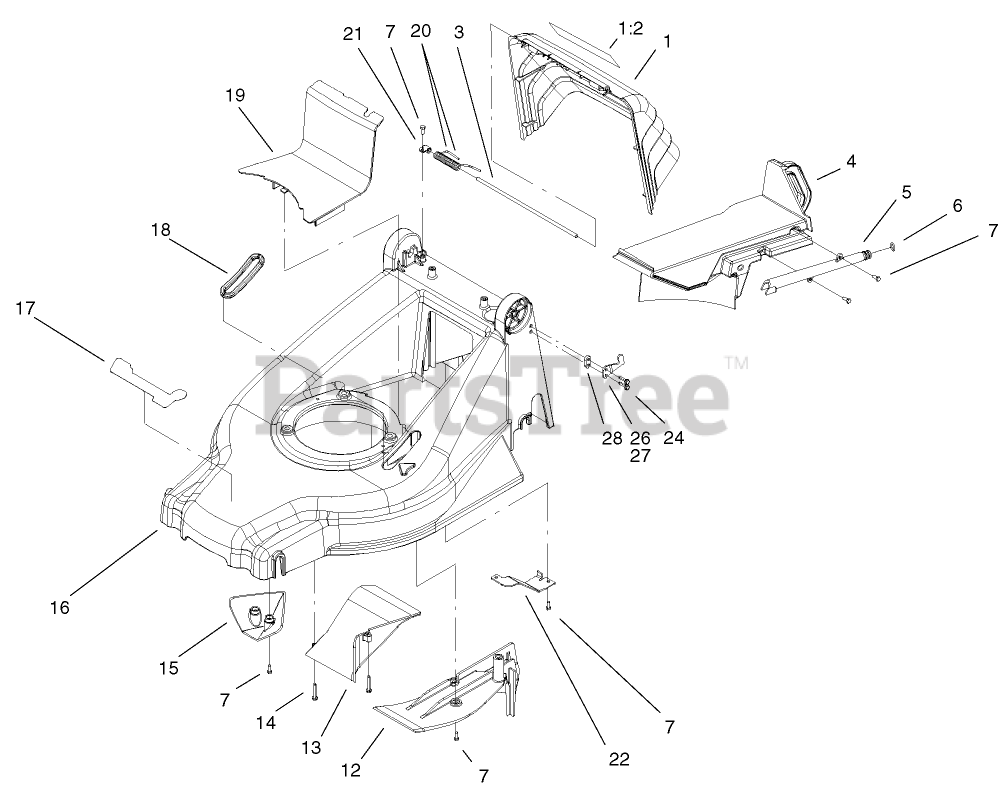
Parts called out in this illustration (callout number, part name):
1	DOOR ASM
3	ROD-PIVOT
4	PLUG-KICKER, RECYCLER
5	FITTING-WASHOUT
6	O-RING
7	SCREW-TAPTITE
12	COVER-KICKER, REAR
13	RAMP-DISCHARGE
14	SCREW-HWH
15	KICKER-FRONT
17	DECAL-RECYCLER
18	BOOT-HOC
19	COVER-BELT
20	SPRING-TORSION
21	CLAMP
22	BRACKET-DECK
24	SCREW-HWH
26	HOOK-LEFT
28	SPACER
